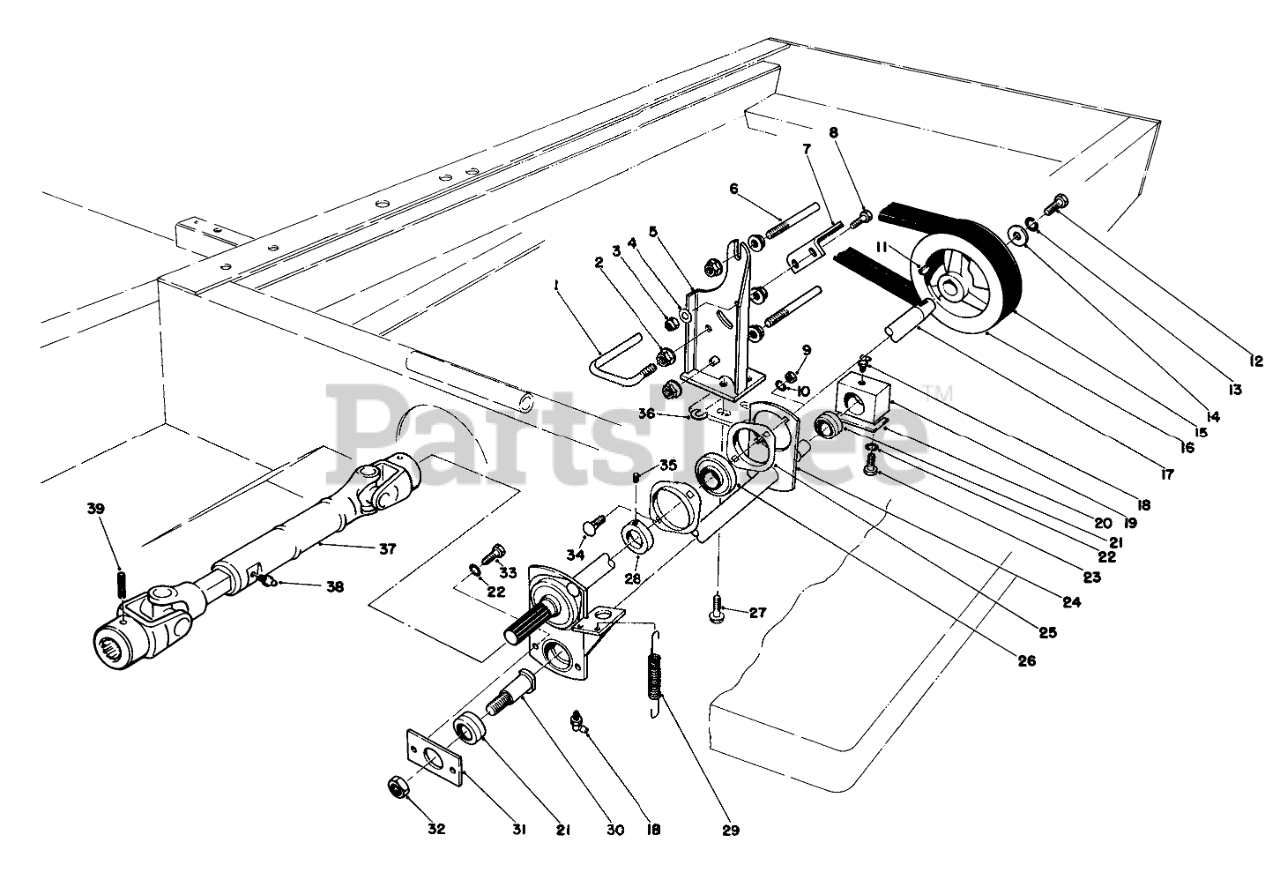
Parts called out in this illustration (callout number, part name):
1	LOWER BELT GUIDE
2	NUT-HHF, WHIZ
3	NUT-LOCK, NI
4	WASHER-PLAIN
5	Bracket-Brake
6	UPPER BELT GUIDE
7	PTO SUPT PAD ASM
8	SCREW-HH
9	NUT-HEX
10	WASHER-LOCK
11	KEY-WOODRUFF
12	SCREW-HH
13	WASHER-LOCK
14	WASHER-FLAT
15	V-BELT
16	Pulley-PTO
17	PTO SHAFT
18	FITTING-GREASE, 90 DEG
19	BEARING HUB PP
20	PTO SHIM BLOCK
21	BEARING
22	WASHER-LOCK
23	SCREW-HH
24	ARM WA - ENGAGE R
25	FLANGE
26	Bearing w/Collar (Incl. Ref. #28 & 35)
27	SCREW-HHF
28	COLLAR-LOCK, BEARING
29	TENSION PTO SPRING R
30	BEARING STUD
31	BRG RETAINER
32	NUT-LOCK, NI
33	SCREW-HH
34	SCREW-CARR
35	SCREW-SET, HSH
36	SPECIAL WASHER
37	UNIVERSAL JOINT
38	FITTING-GREASE
39	PIN-ROLL
